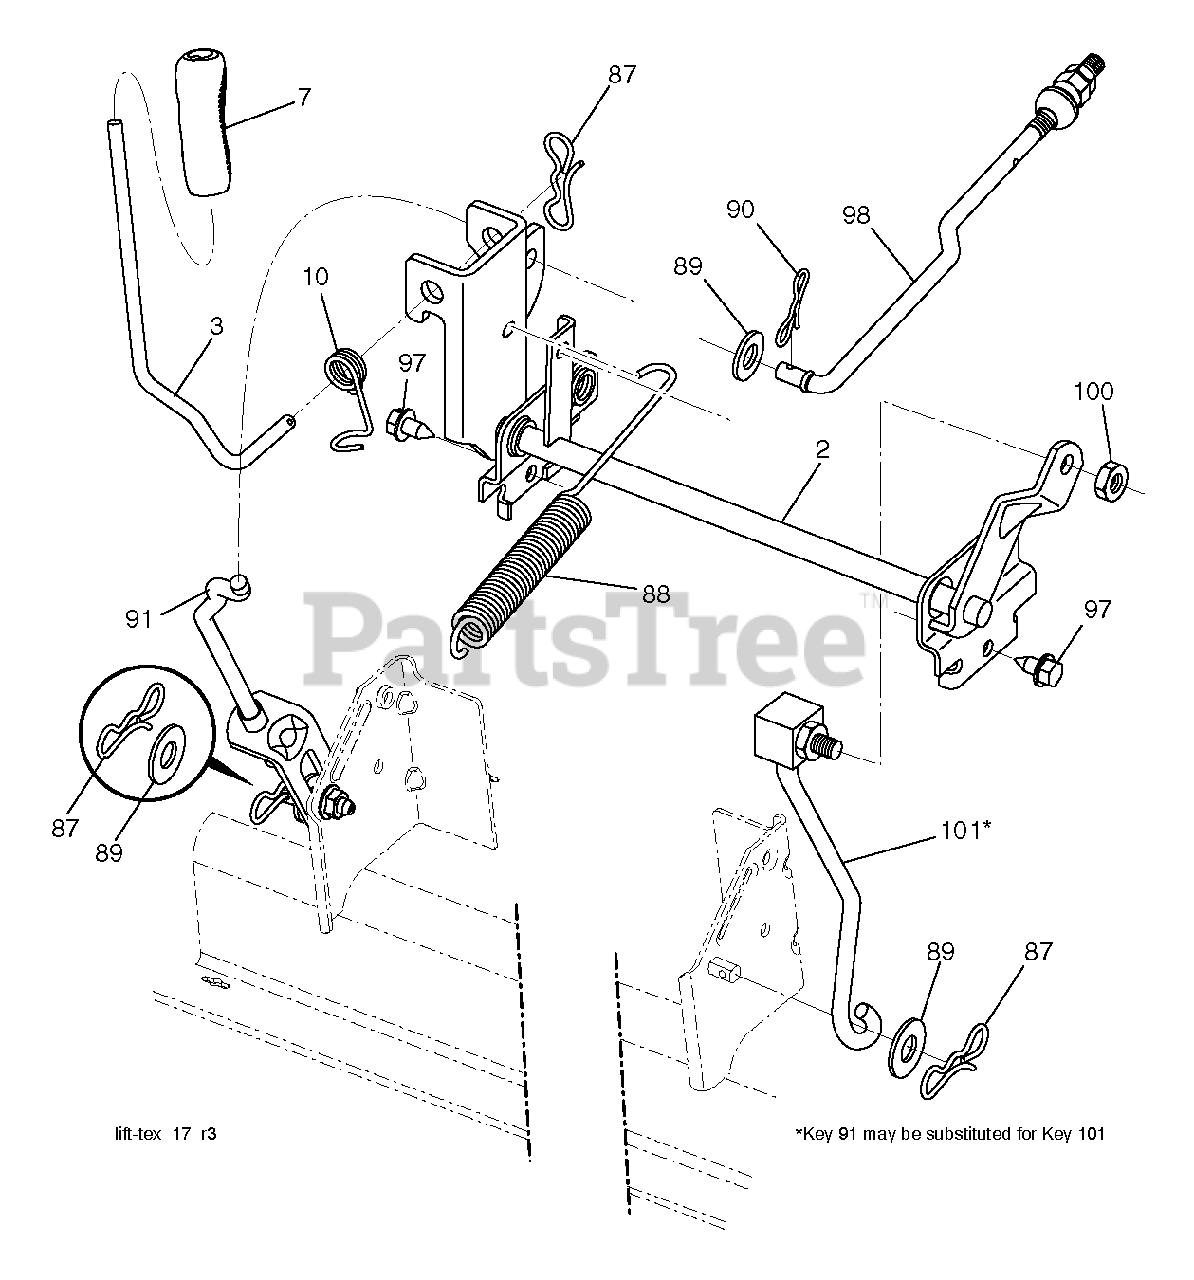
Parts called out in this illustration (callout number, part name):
2	SHAFT.ASM.CROSS.LIFT
3	LEVER.LIFT.HANDLE.LT
7	GRIP.HANDLE.LIFT.PVC.BLACK
10	SPRING.TORSION.LIFT.HANDLE
87	PIN.COTTER.7/16.BOW TI.
88	SPRING.LIFT.ASSIST
89	WASHER.CLEAR.ZINC
90	PIN.COTTER.5/16.BOW TI
91	LINK.LIFT.ASM.REAR.GT.
97	SCREW, 3/8-16X3/4
98	LINK.ASSY.FRONT.MWR.SUSP
100	LOCKNUT
101	LINK.ASSY.BLACK.431
